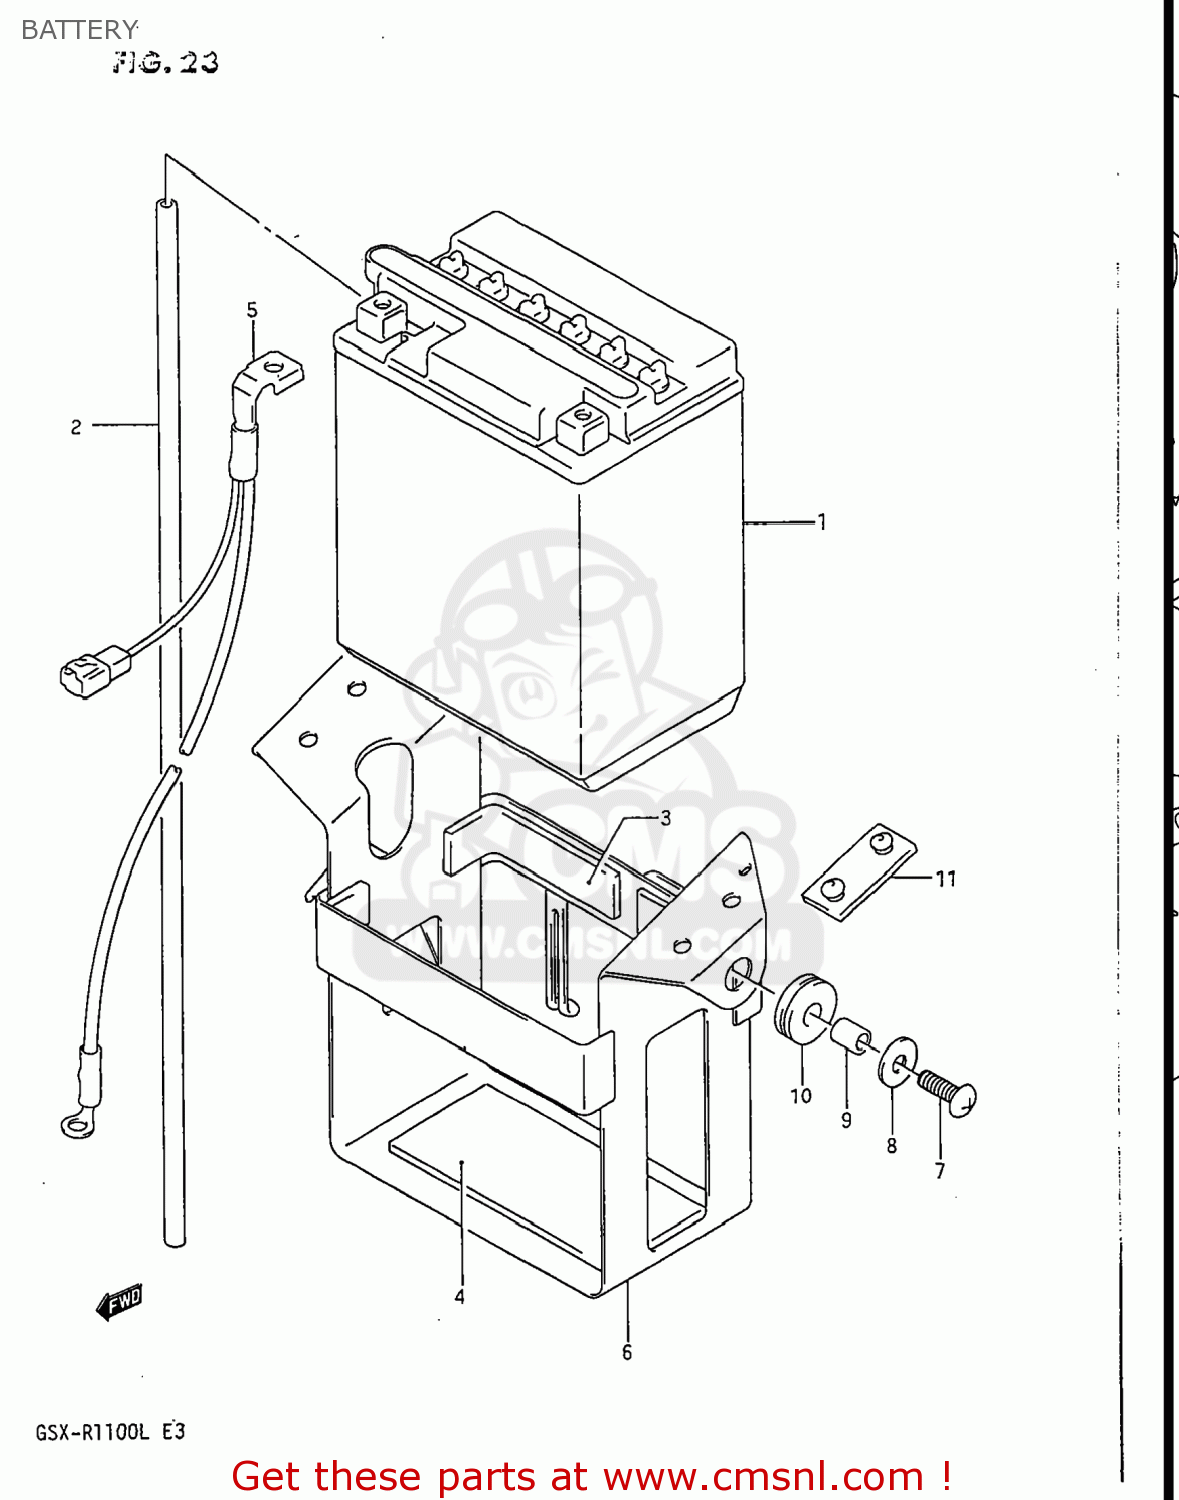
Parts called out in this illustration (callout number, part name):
1	BATTERY ASSY (12V)
2	HOSE,BATTERY EXHAUST
3	PROTECTOR,20X9
4	PROTECTOR(170X95X3.0)
5	WIRE,BATTERY MINUS LEAD
6	HOLDER,BATTERY
7	SCREW
8	WASHER
9	SPACER
10	CUSHION
11	CUSHION
